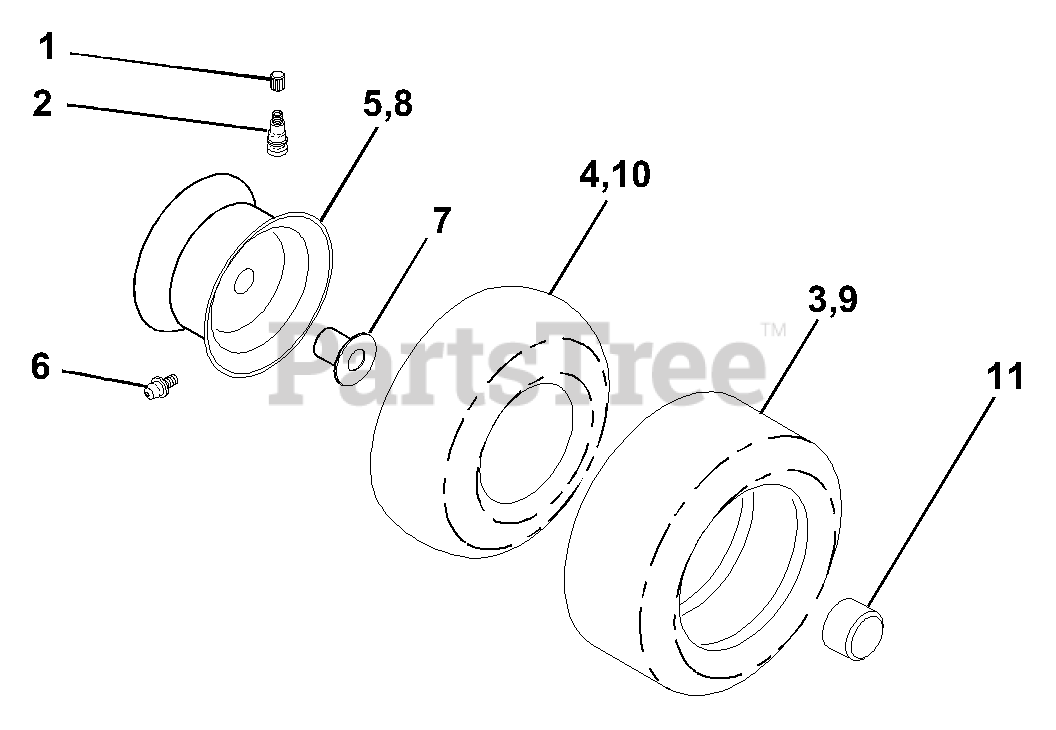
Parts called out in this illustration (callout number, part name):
1	Cap Valve Tire
2	Stem Valve
3	Tire F Ts 15 X 6 0 - 6 Service
4	Tube Front
5	Rim Asm 6" front Silver Service
6	Fitting Grease
7	Bearing Flange
8	Rim Asm 8" rear Silver Service
9	Tire R Ts 18x8 5-8 C Service
10	Tube Rear
11	Cap Axle Blk 1 50 X 1 00
